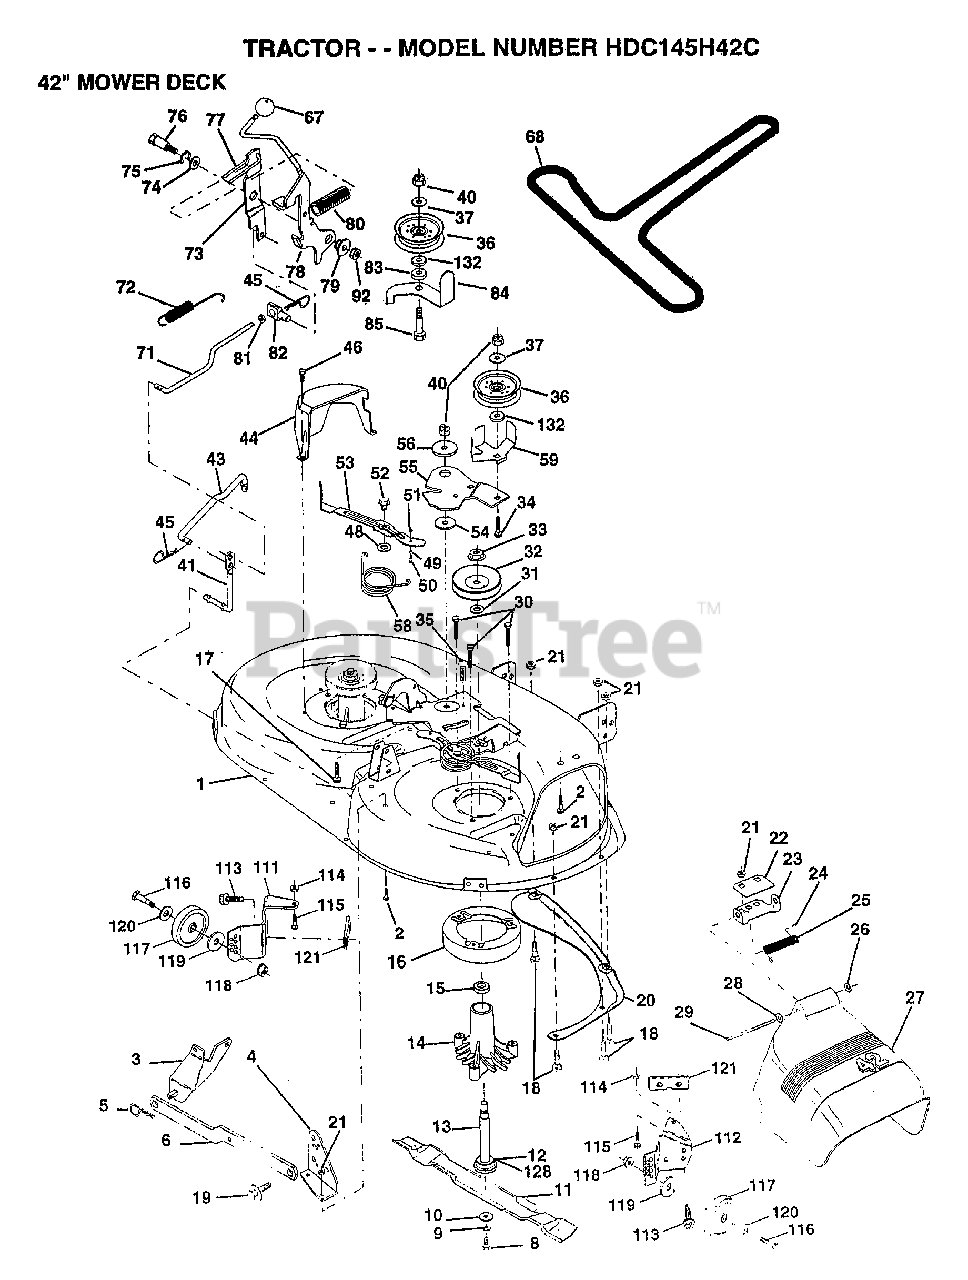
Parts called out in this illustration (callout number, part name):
1	DECK.WELD.42.
2	BOLT
3	BRKT ASM SWAY BAR
4	BRKT DECK SW BAR
8	BLADE BOLT
10	WASHER.HARD.BLADE
11	"BLADE.42"" HIPERF"
12	BEARING.BALL
14	HSG ASM MANDREL
15	BEARING
16	STRIPPER RND MWR
17	BOLT RDHD 3/8-16
18	BOLT
19	BOLT SHD 5/16-18
22	STIFFENER BRKT
23	DEFLECTOR BRKT
24	CAP-SLEEVE LT
25	SPRING TORSION
26	NUT PUSH M
27	DEFLECTOR.SHIELD
29	WASHER
29	HINGE ROD
31	WASHER
32	PULLEY.MANDREL.42
34	BOLT
35	XMAS TREE FASTNER
36	FLAT IDLER PULLEY
37	WASHER
41	PIVOT ROD
43	ROD CLUTCH W/NIBS
44	GUARD MAND LH BLK
45	RETAINER M
46	SCREW.1/4-20X5/8
48	HARD SMALL WASHER
49	ROLLER ASM-CAM
50	SHOULDER BOLT
51	LOCKNUT
52	BOLT.SHLD.5/16-18
54	HARDENED WASHER
55	ARM-IDLER
56	SPACER RETAINER
58	SPRING TORSN BRAK
58	BELT.V.T-PATH
59	GUARD IDLER TUV
67	KNOB T(3/8 HOLE)
71	ROD CLUTCH 38/42
72	RETURN SPRING
73	CLUTCH ARM SECOND
74	WASHER
75	RING
76	SHOULDER BOLT
77	SPRING KEEPER
78	LEVER ASM-CLUTCH
79	BUSHING
80	SPRING.CLUTCH.MWR
81	NUT
82	TRUNION ADJ
83	WASHER
84	"KEEPER-BELT,FIXED"
85	BOLT RDHD 3/8-16
92	NUT
111	BRACKET.GWHL.LH.
112	BRACKET.GWHL.RH.
113	SCREW
116	BOLT M
117	WHEEL.GAGE.BLK.PL
118	LOCKNUT
119	WASHER
120	WASHER
121	BRACKET.EXTRD.GWL
128	WASHER.FELT.
132	WASHER GT
